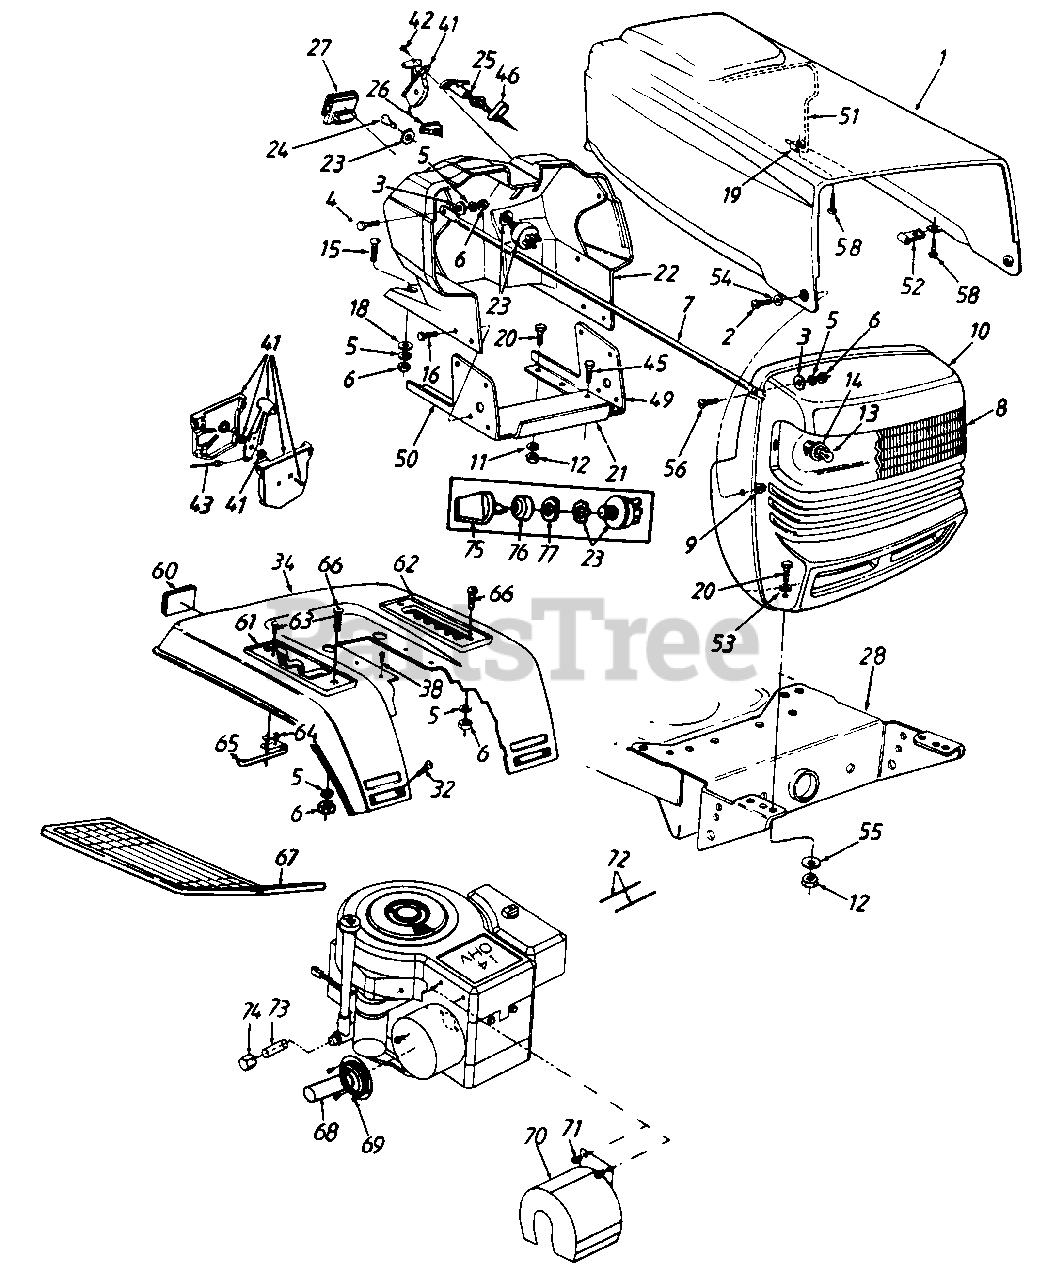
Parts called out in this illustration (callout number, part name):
3	Fl-Wash .28" I.D. x .75" O.D.
4	Hex Bolt 1/4-20 x .62" Lg.
5	L-Wash. 1/4" I.D.
6	Hex Nut 1/4-20 Thd.
9	Flange L-Nut 1/4-28 Thd.
12	Hex Nut 5/16-18 Thd.
13	Lamp
14	Socket
15	Carriage Bolt 1/4-20 x .75" Lg.
16	Hex Wash. Hd. TT-Tap Scr. 1/4-20 x .5" Lg.
18	Bolt Retainer 1/4" I.D.
19	Speed Nut #10-24 Thd.
20	Hex Bolt 5/16-18 x .75" Lg.
23	Ignition Switch
24	Ignition Key
25	Choke Control
26	Light Switch
27	Ammeter
32	Truss Mach. Scr. 1/4-20 x .5" Lg
41	Throttle Box Ass'y.
42	Truss Mach. AB-Tap Scr. #10 x .5" Lg.
43	Throttle Control Wire
45	Hex Wash. Hd. B-Tap Scr. 5/16-18 x .5" Lg.
46	Choke Retainer
52	Flat Fastener (Special)
53	Fl-Wash. .344" I.D. x 1" O.D.
54	Spr. Wash .39" I.D. x .62" O.D.
55	Bell-Wash .345" I.D. x .88" O.D.
56	Pan Hd. Scr. 1/4-20 x .75" Lg.
58	Truss Mach. 8-Tap Scr. #10 x .5" Lg.
60	Reflector
61	Forward/Reverse Index Brkt.
62	7-Speed Index Brkt.
63	Hex Wash. Hd. AB-Tap Scr. #8 x .5" Lg.
64	Insulator Nut Plate
65	Reverse Safety Switch
66	Truss Mach. Scr. 1/4-20 x 75" Lg.
67	Foot Pad - L.H.
68	Exhaust Pipe Ass'y.
69	Hex Wash. Hd. F-Tap Scr. #8-32 x .38" Lg.
70	Heat Shield Ass'y.
71	Hex Wash. Hd. Scr 1/4-20 x .5" Lg.
72	Cable Tie
73	Pipe Nipple 3/8-18 NPT x 2" Lg.
74	Cap - Oil Drain
75	Ignition Key
76	Ignition Switch Cap
77	Ignition Switch Nut
